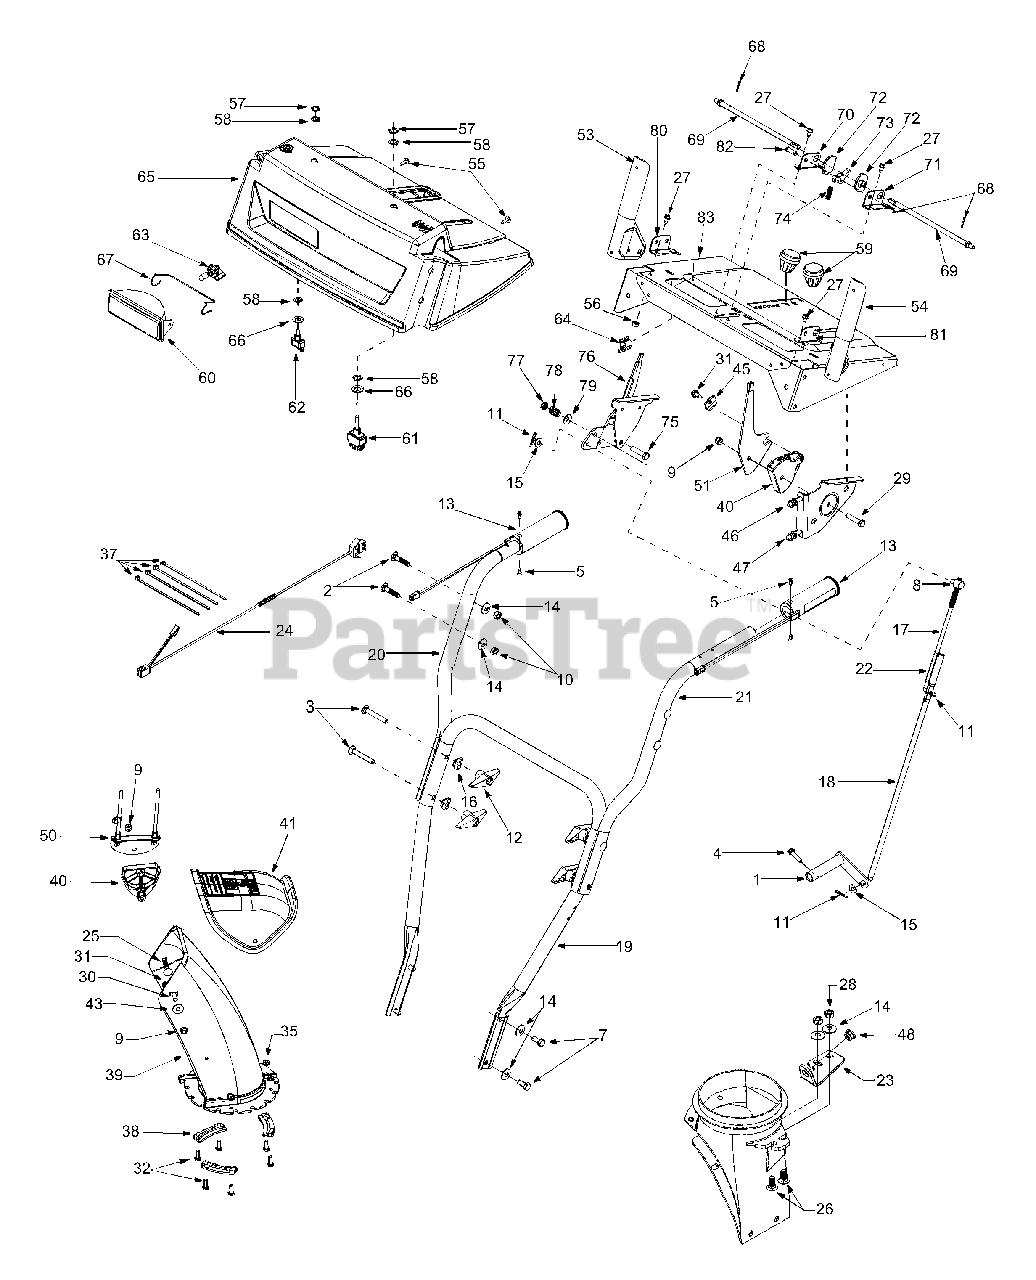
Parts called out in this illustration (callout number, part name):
3	Carriage Bolt 5/16-18 x 2.25"
4	TT Screw 1/4-20 x 1.00"
5	C-Sunk Screw #10-16x .625"
7	Hex Screw 5/16-18 x .75"
8	Ferrule
9	Hex Lock Nut 5/16-18
10	Hex Nut 5/16-18
11	Cotter Pin
12	Handle Knob
13	Heated Grip
14	Belleville Washer
15	Flat Washer
16	Saddle Washer
17	Shift Rod: Upper
18	Shift Rod: Lower
24	Electric Harness: Lower
25	Carriage Bolt: 5/16-18 x 1.5"
26	Carriage Bolt: 5.16-18 x .75"
27	TT Screw: 1/4-20 x .50"
28	Hex Nut 5/16-18
29	Hex Screw: 5/16-18 x 1.5"
30	Carriage Bolt, 5/16-18x .75"
31	Hex Screw AB:1/4-15 x .75"
32	Hex Screw, 1/4-20 x .75"
35	Hex Flange Lock Nut
37	Cable Tie
38	Chute Flange Keeper
39	Lower Chute
40	Cable Guide: Chute Tilt
41	Upper Chute
43	5/16 Washer
45	Special Washer
46	Control Cable
47	Control Cable
48	Plastic Bushing
53	Handle Assembly RH
54	Handle Assembly LH
55	Special Hex Screw
56	Hex Sems Nut: 1/4-20
57	Hex Nut
58	Lock Ring: Toggle Switch
59	Shift Knob
60	Lamp Housing
61	Toggle Switch: Double Throw
62	Toggle Switch: Single Switch
63	Halogen Lamp: 50W, 12V
64	Mounting Clamp
65	Handle Panel
66	Flat Washer
67	Headlight Retainer
68	Cotter Pin: 3/32 x .75"
69	Cam Rod
73	Handle Lock Pawl
74	Compression Spring: .36 x 1.0
75	Hex Cap Screw: 3/8-24 x 1.5
78	Comp. Spring: .39 x .6 x .88
79	Bell Washer
82	Clevis Pin
